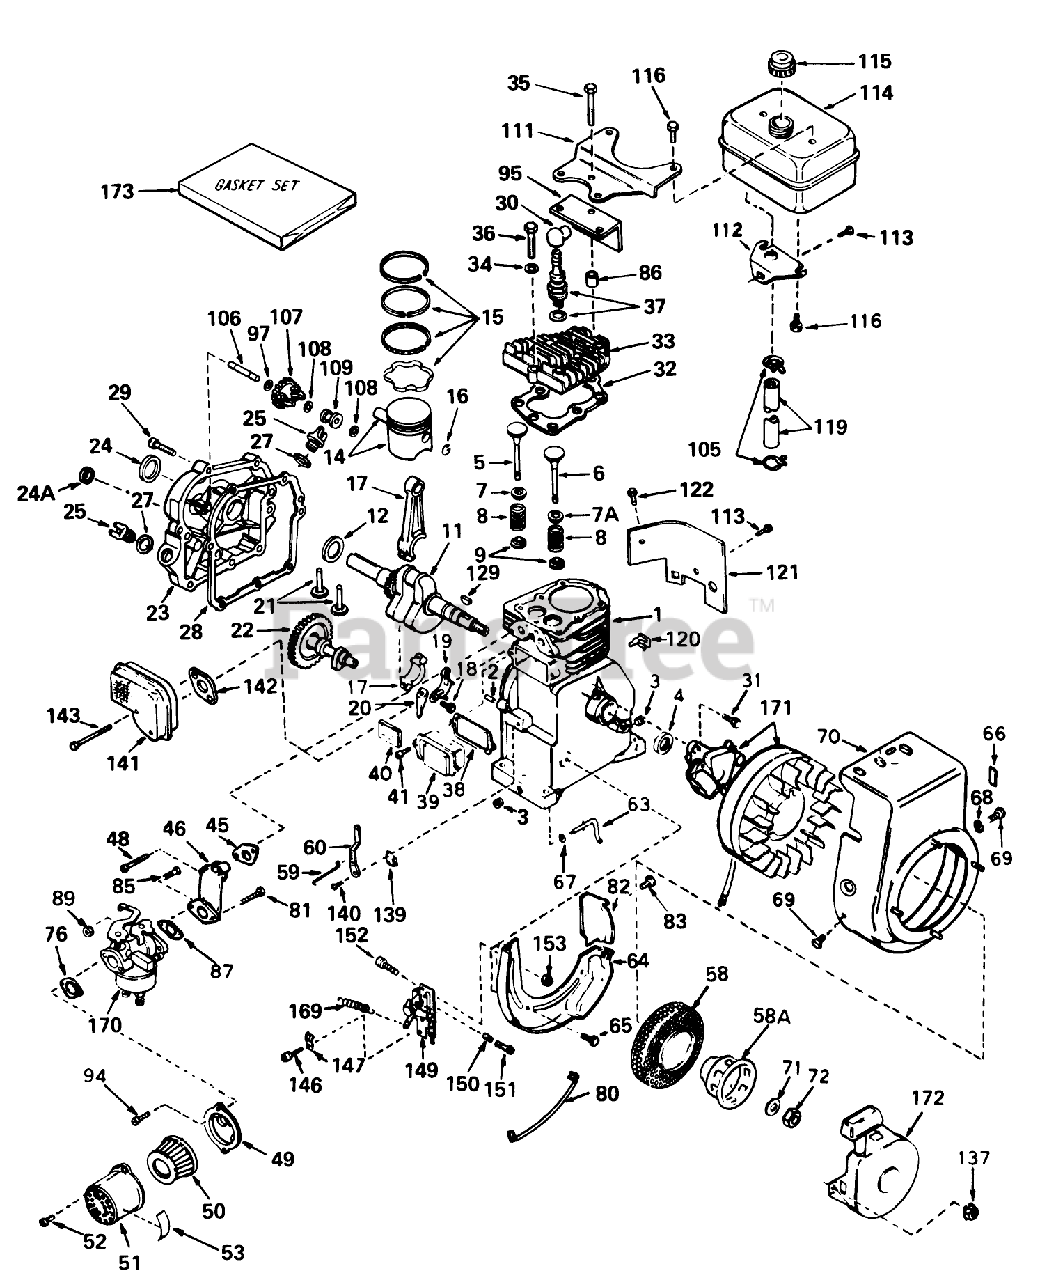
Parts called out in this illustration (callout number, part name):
1	Cylinder Assy. (Incl. Nos.2, 34)
2	Pin-Dowel
3	Plug-Drain, Oil (SQH 1/4-18)
4	Seal-Oil
5	Valve, Intake (Standard) (Incl. Nos. 7, 9 10)
5	Valve, Intake (1/32" Oversize) (Incl. Nos. 7, 9 10)
6	Valve, Exhaust (Standard) (Incl. Nos. 8, 9 10)
6	Valve, Exhaust (1/32" Oversize) (Incl. Nos. 8, 9 10)
7	Cap-Upper Valve Spring
7A	Cap, Upper Valve Spg (Exhaust)
8	Spring-Valve
9	Cap-Valve, Spring
11	Crankshaft
12	Washer-Thrust
14	Piston Pin Assembly (Incl. 2 of No. 14)(Std.)
14	Piston Pin Assembly (Incl. 2 of No. 14)(.010 Oversize)
14	Piston Pin Assembly (Incl. 2 of No. 14)(.020 Oversize)
15	Ring Set-Piston Std.
15	Ring Set-Piston .010 oversize
15	Ring Set-Piston .020 oversize
16	Ring-Retaining, Piston Pin
17	Rod Assy., Connecting (Incl. Nos. 18 19)
18	Connecting Rod Bolt
19	Plate Lock
20	Dipper-Oil
21	Lifter-Valve
22	Camshaft (Compression Release) (Extended)
23	Cover, Cylinder (Incl. Nos. 24, 24A, 25, 106 148)
24	Seal-Oil
24A	Seal, Oil
25	Plug-Fill, Oil
27	Gasket
28	Gasket-Cylinder Cover
29	Screw
30	Cover-Spark Plug
31	Screw
32	Oil Fill Tube
33	Head Cylinder
34	Washer
35	Screw Hex Hd. Cap
36	Screw
37	Plug, Spark (J17LM or equiv.)
38	Gasket Breather
39	Breather Assembly (Incl. Nos. 52 84)
40	Element-Breather
41	Screw
45	Gasket-Intake
46	Pipe, Intake
48	Screw
49	Bracket, Air cleaner
50	Element
51	Body
52	Screw
53	Decal
58	Screen-Starter
58A	Cup, Starter
59	Link-Governor to Throttle
60	Lever-Governor
63	Rod-Governor
64	Baffle-Blower Housing
65	Screw (1/4-20x19/32)
66	Decal, Name Instruction
67	Washer-Flat
68	Washer
69	Screw
70	Housing Blower
71	Washer-Spring
72	Hex Nut
76	Gasket
80	Wire, Ground
82	Baffle-Extension
83	Screw-Hex Washer Hd.
85	Screw-Fil. Hd.
86	pacer
87	Gasket
89	Nut and Lock Washer (1/4-28)
94	Screw (10-32 x 1/2)
95	Baffle-Heat
97	Washer-Flat
105	Clamp-Line, Fuel
106	Shaft-Governor
107	Governor Gear ASM
108	Ring-Retaining
109	Spool-Governor
111	Bracket, Fuel tank
112	Bracket, Fuel Tank Lower
113	Screw (1/4-20x19/32)
114	53023/VAR.10/16HP O
115	Cap, Fuel
116	Screw (1/4-15x7/8)
119	Line-Fuel
120	Clip-Wire
121	Extension-Blower
122	Screw
129	Key Flywheel
137	Nut and Lock Washer (1/4-28)
139	Clamp-Lever, Governor
140	Screw
141	Muffler
142	Gasket-Exhaust
143	Screw, Hex hd. cap
146	Screw (10-32 x 3/8)
147	Conduit
149	Bracket Assy., Control (Incl. Nos. 149, 150, 151 152)
150	Spring-Compression
151	Screw
152	Screw, Hex Slotted Hd.
153	Nut-Lock
169	Spring-Extension
170	Carburetor (Incl. No. 87)
171	Magneto
172	Starter, Rewind
173	Gasket Set
